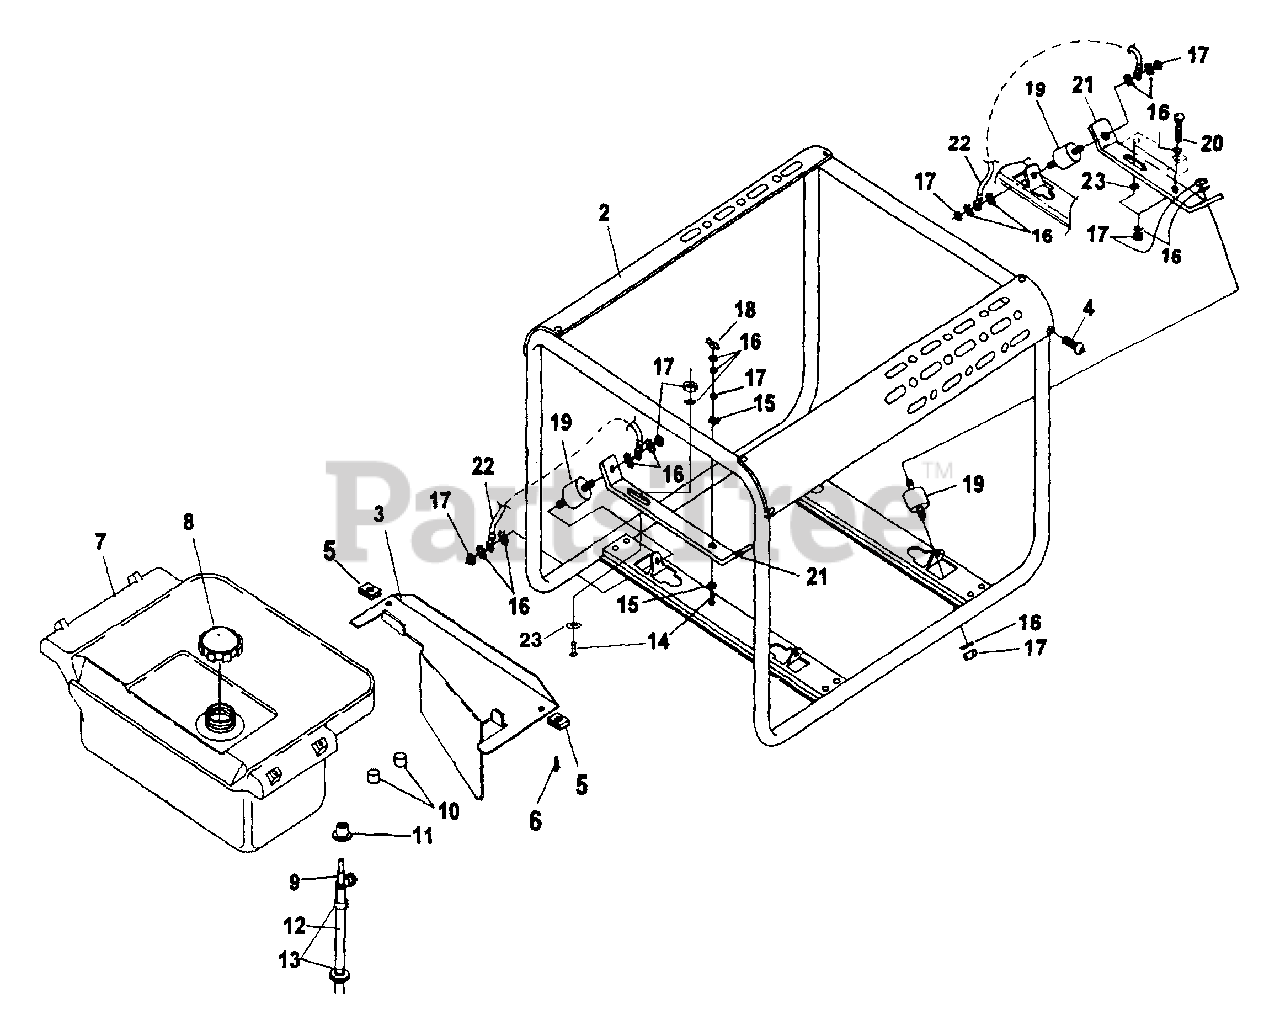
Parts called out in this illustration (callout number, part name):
2	BRACE-Tank Support
3	SHIELD-Fuel Tank
4	SCREW-Torx (10-24 X 1/2")
5	NUT-Speed
6	SCREW-Pan Hd. (8-32 X 3/8")
7	FUEL TANK (3 Gal.)
8	CAP-Fuel (2 1/4" Dia.)
9	VALVE-Fuel
10	PAD-Fuel Tank
11	BUSHING
12	HOSE-Fuel (8")
13	CLIP-Hose
14	SCREW-Hex Hd. (5/16-18 X 1 1/4")
15	WASHER-Flat (5/16)
16	WASHER-Lock (int.)
17	NUT-Hex (5/16-18)
18	NUT-Wing (5/16-18)
19	ISOLATOR
20	SCREW-Hex Hd. (5/16-18 X 1 3/4")
21	SUPPORT - ENG./GEN.
22	GROUND STRAP
23	WASHER-Flat
